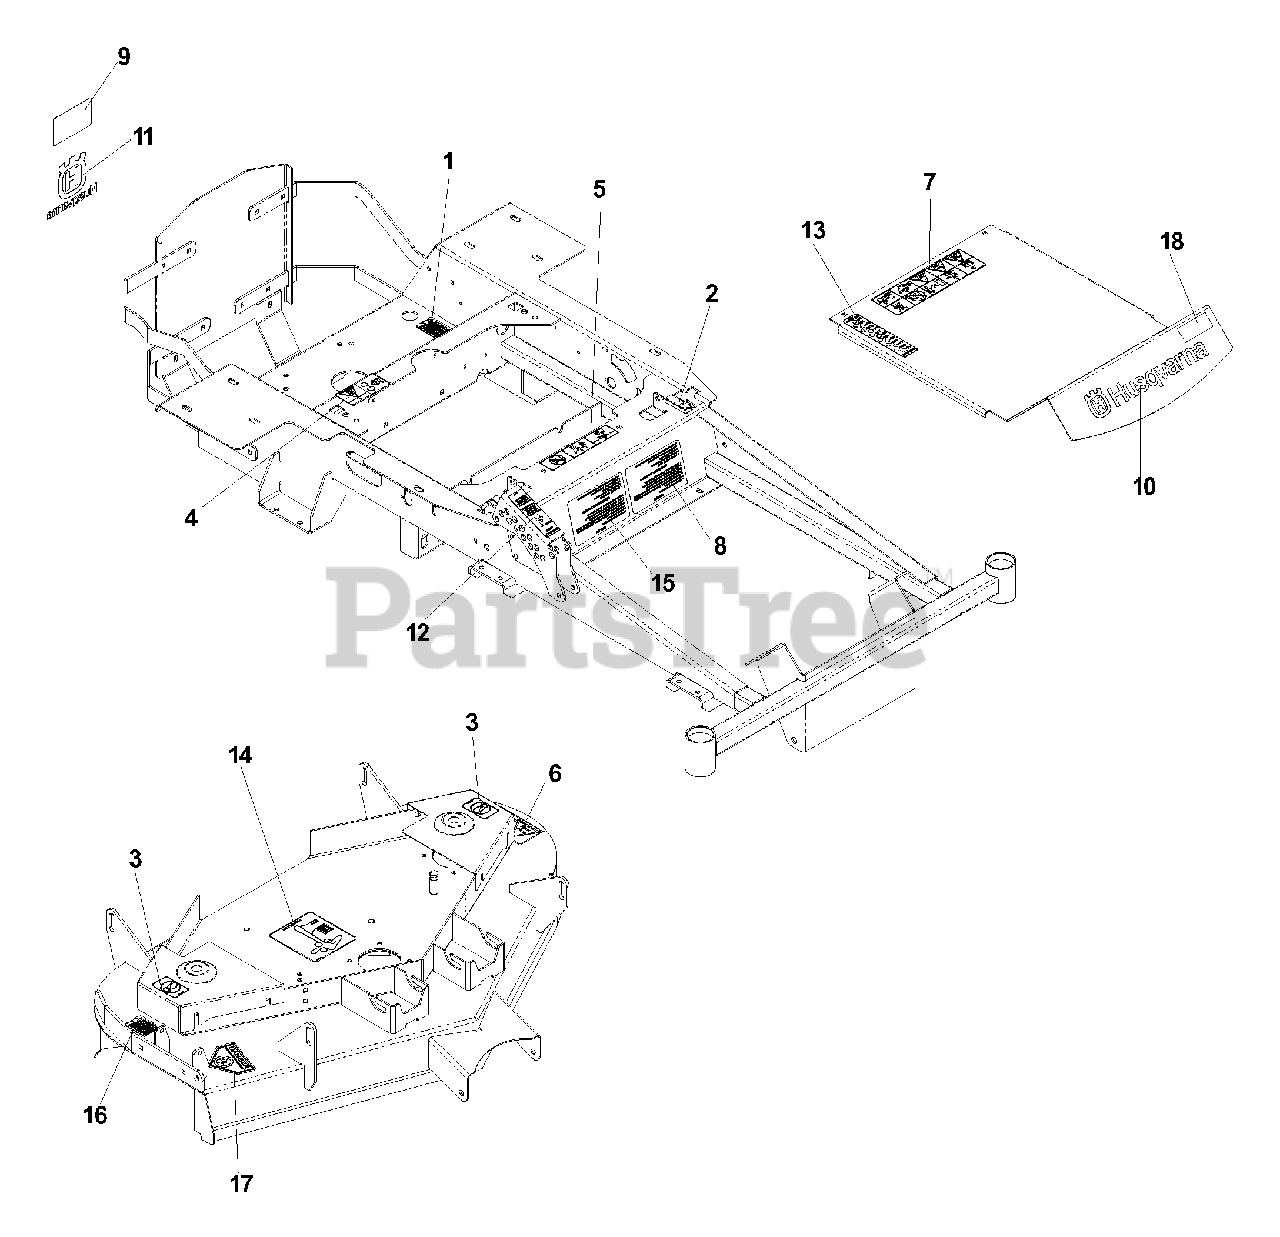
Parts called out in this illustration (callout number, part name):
1	DECAL, PROP 65
2	DECAL, MOTION CONTROL
3	DECAL, EURO NO STEP
4	DECAL, EURO DANGER BELT
5	DECAL, EURO BATTERY WARNING
6	DECAL, EURO SEVERING
7	DECAL, WARNING
8	DECAL, START
9	DECAL, DO NOT TOW
10	DECAL, HUSQVARNA
11	DECAL, CROWN
12	DECAL, TRANSPORT RELEASE
13	DECAL, HEIGHT ADJUSTMENT
14	DECAL, BELT ROUTING
15	DECAL, WARNING
16	DECAL, CAUTION
17	DECAL, WARNING
18	DECAL
